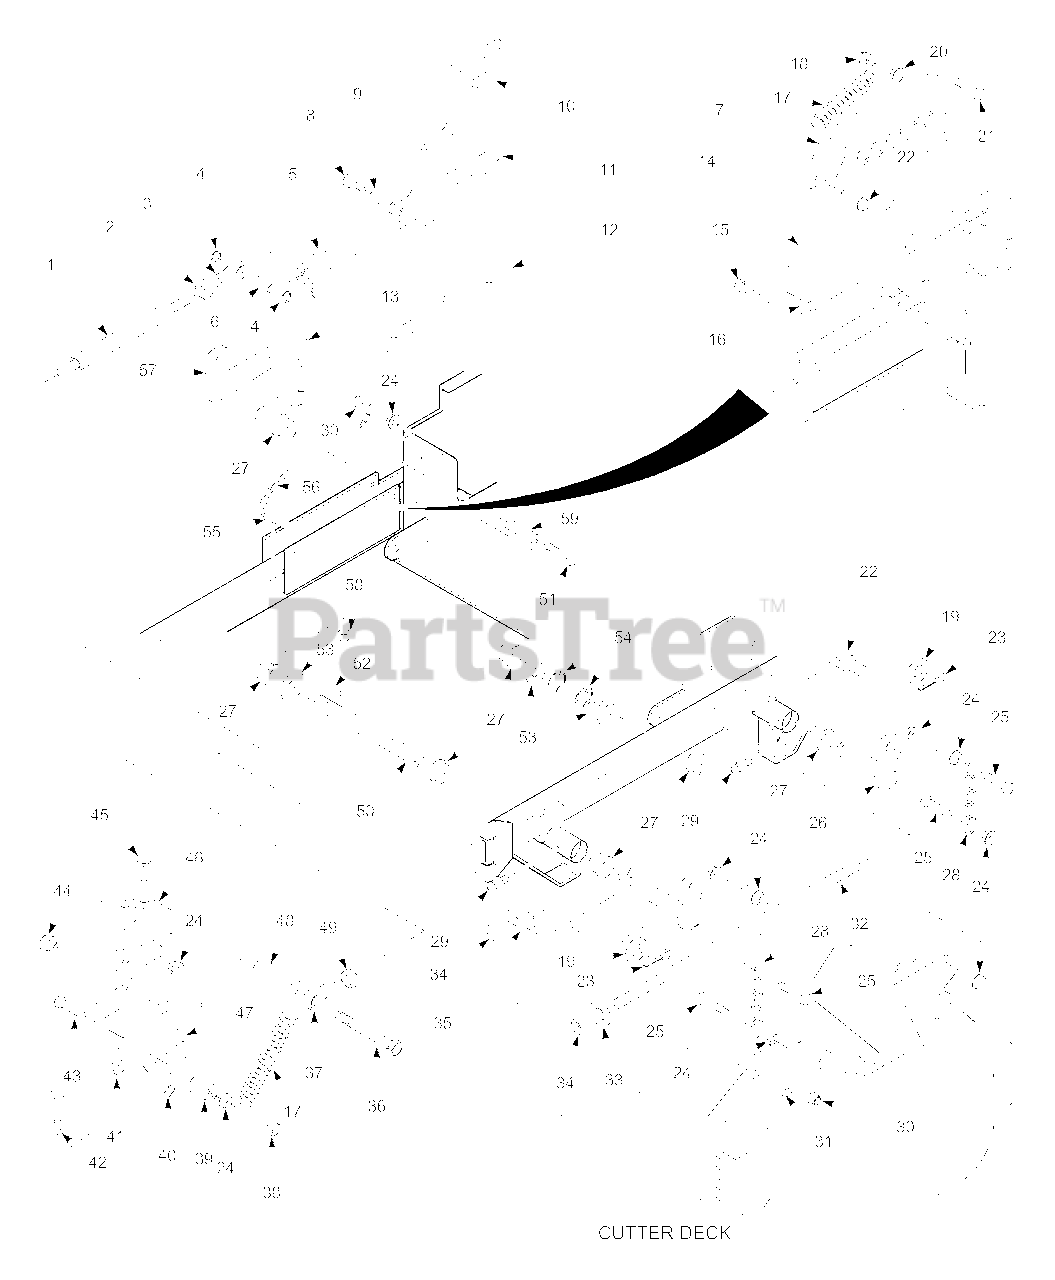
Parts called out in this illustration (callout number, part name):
1	Rod, Deck Lift Linkage
2	Nut, Jam 1/2-20 LH Thread
3	Rod End, 1/2-20 Female Thread
4	Retaining Ring, 1/2" External "E"
5	Slide, Deck Height Adjust
6	Pin, Deck Lift
7	Bracket, Cutting Height Adjustment
8	Bolt, Shoulder 1/2-3/4"
9	Bushing .502 ID
10	Grip, Deck Latch Lever
11	Lever, Deck Latch
12	Slide, Cutting Height
13	Screw, Cap 5/16-18 x 3" FHHS
14	Guide, Short
15	Bolt, Carriage 5/16-18 x 1"
16	Guide, Long
17	Spring, Helper
18	Nut, 3/8-16 Center Lock
19	Flatwasher, 5/8-.656 x 1.312 x .095
20	Nut, 3/8-16 Serr. Flange
21	Bolt, Hex Head 3/8-16 x 1-1/4"
22	Swivel Joint LH
23	Cotter Pin, 3/16 x 1"
24	Nut, Serr. Flange 3/8-16
25	Bolt, Hex Head 3/8-16 x 1-1/2"
26	Bellcrank, RH Rear
27	Bushing
28	Chain
29	Grease Fitting, 1/4-28 Self Tap
30	Nut, Elastic Stop 3/8-16
31	Flatwasher, 3/8-.391 x .938 x .105
32	Stud, 5/8-11 x 22"
33	Flatwasher, 5/8-.656 x 1.312 x .095
34	Nut, 5/8-11 UNC
35	Swivel Joint RH
36	Bolt, Hex Head 1/2-13 x 5"
37	Rod End, 1/2-20 Female
38	Lock Nut, 3/8-16
39	Spacer
40	Set Screw, 5/16-18 x 1/4"
41	Nut, Elastic Stop 7/16-14
42	Bolt, Hex Head 7/16-14 x 2-1/2"
43	Bolt, Hex Head 3/8-16 x 2-1/2"
44	Lock Nut, 1/4-20
45	Bolt, Carr. 3/8-16 x 1"
46	Foot Pedal
47	Foot Pedal Weldment
48	Spacer
49	Nut, 1/2-20 UNF-2B
50	Bellcrank, LH Front
51	Bolt, Hex Head 3/8-16 x 3-1/2"
52	Key, 1/4 x 1/4 x 1-1/4"
53	Flatwasher, 1.062 x 1.5 x .048
54	Retaining Ring, 1" Ext.
55	Ring Pin, 1/2 x 3.30"
56	Lanyard, Deck Height Pin
57	Bellcrank, LH Rear
58	Nut, Elastic Stop 5/16-18
59	Spacer
